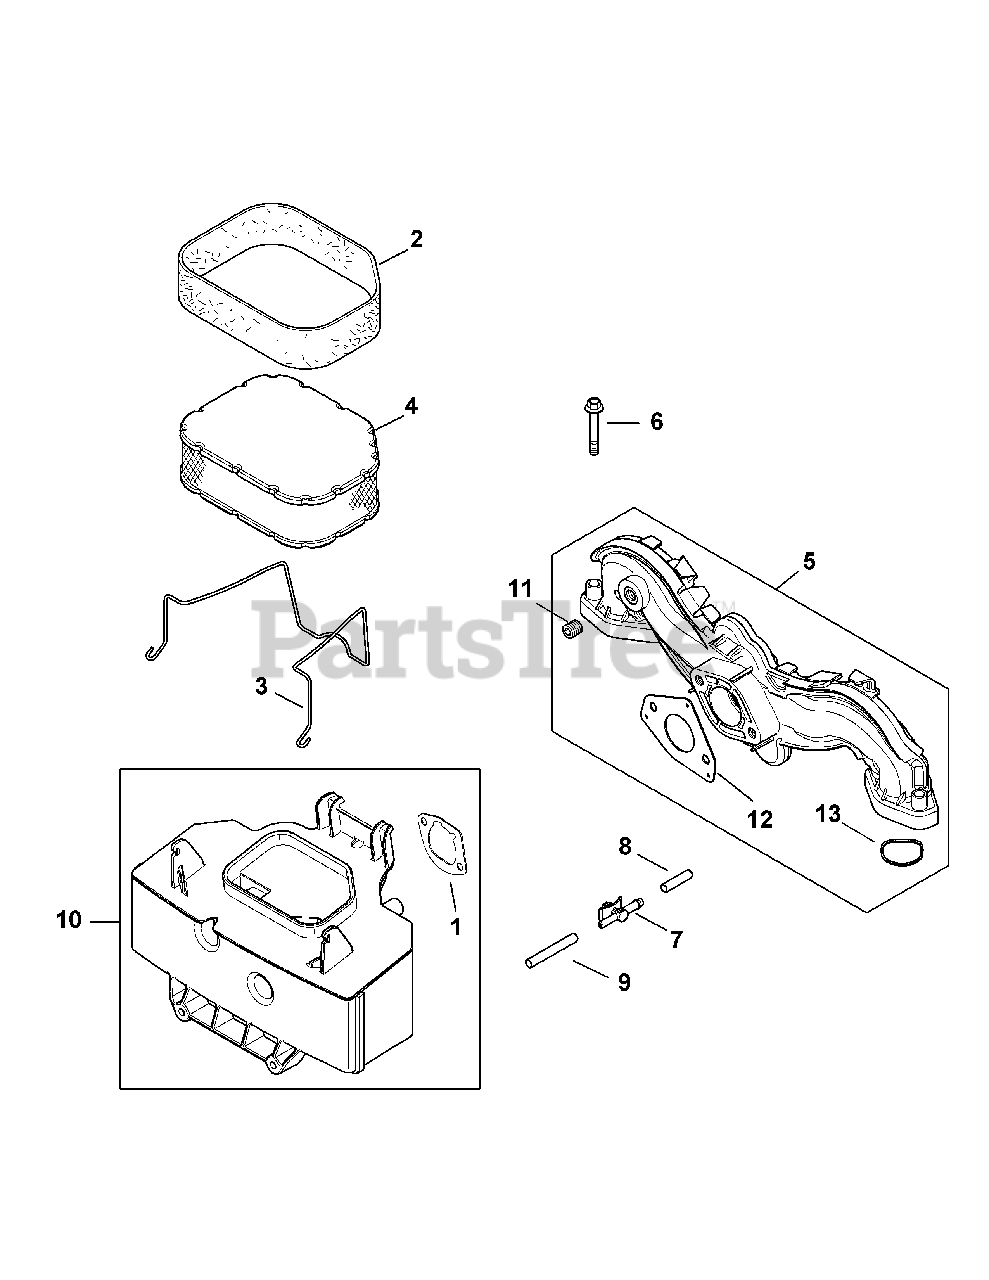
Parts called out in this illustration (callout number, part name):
1	Air Cleaner Base Gasket
2	Pre-Cleaner Element
3	Air Cleaner Element Latch
4	Air Filter & Pre-Cleaner Elements
5	Intake Manifold Kit
6	Flange Screw, M6 x 1.0 x 40
7	Evaporative Connector
8	Evaporative Mask
9	Evaporative Hose, 20"
10	Air Cleaner Base
11	Pipe Plug, 1/8
12	Carburetor Gasket
13	Intake Port O-Ring
